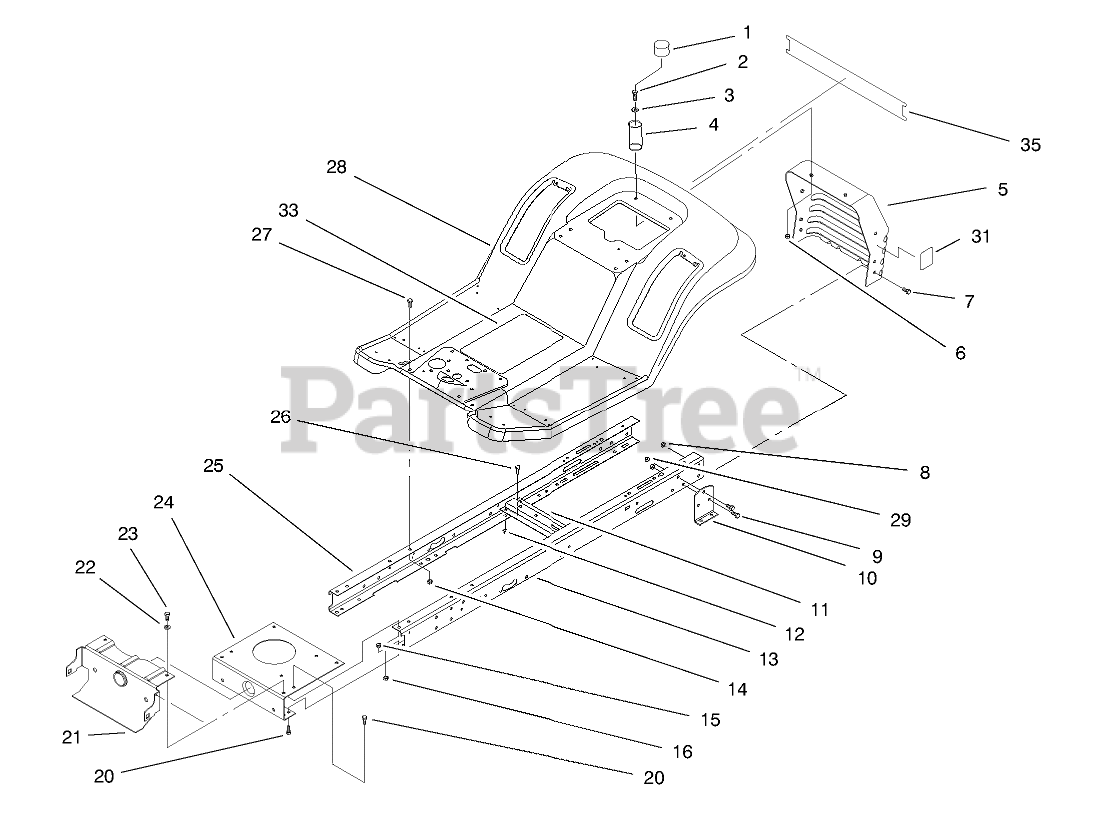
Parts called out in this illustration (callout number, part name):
1	CAP-PROTECTOR
2	SCREW-HH
3	WASHER-PLAIN
4	SPRING-COMPRESSION
5	Panel-Rear
6	NUT-LOCK, NI
7	SCREW-HH
8	NUT-LOCK, NI
9	SCREW-HH
10	BRACKET-TRANSAXLE, MOUNTING
11	BRACKET-IDLER PIVOT
12	NUT-LOCK, NI
13	Frame Rail-LH
14	NUT-LOCK, NI
15	NUT-LOCK, NI
16	NUT-LOCK, NI
20	SCREW-HH
21	Support-Front Axle
22	WASHER-PLAIN
23	SCREW-HH
24	PLATE-MOUNTING, ENGINE
25	Frame Rail-RH
26	SCREW-HH
27	SCREW-HH
28	Body-Rear
29	NUT-LOCK, NI
31	DECAL - DUMP VALVE
33	DECAL-INSTRUCTION
35	DECAL-REAR BODY 1438 HXL
